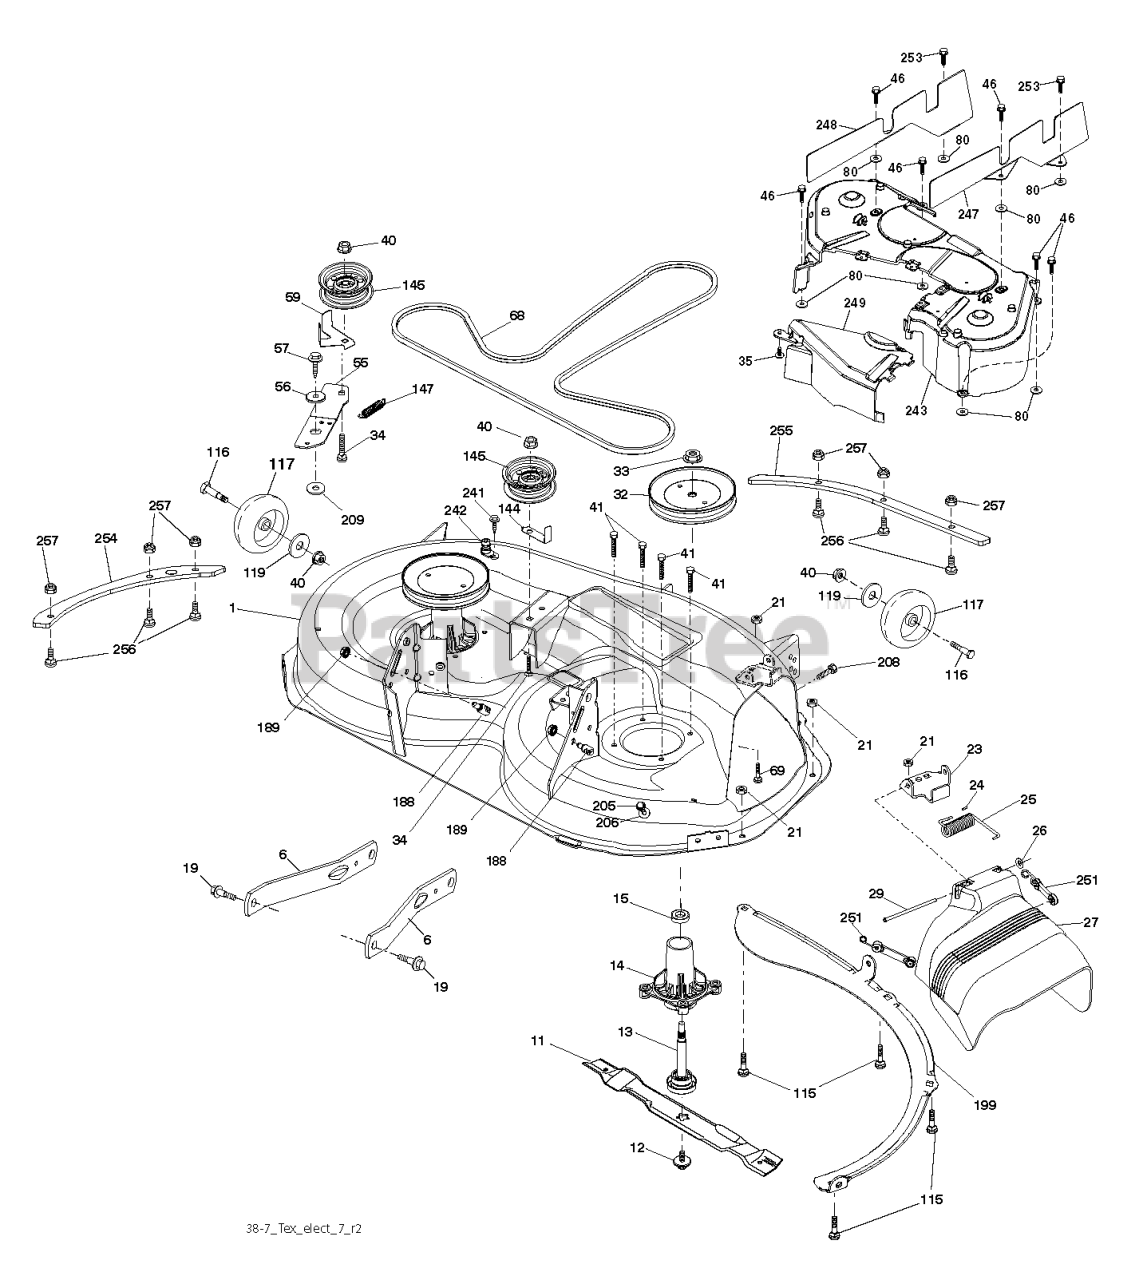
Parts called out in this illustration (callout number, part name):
1	DECK SVC 38" 199770X498
6	ARM.SUSPENSION.MOWER.R
11	BLADE.2 IN 1.38"DECK
12	SCREW.SEMS.7/16-20X1.HEX.HEAD
13	SHAFT ASM.MNDRL.N/GREASEABLE
14	RP.HOUSING.MANDREL.4PT.
15	BEARING.MANDREL.TOP.EXTENDED
19	BOLT.SHOULDER
21	LOCKNUT
23	BRKT.DEFLECTOR.38"2005+
24	CAP-SLEEVE LT
25	SPRING.TORSION.DEFLECT
26	NUT PUSH M
27	SHIELD ASM.DFLCTR MWR.38-7"BLK
29	ROD.HINGE
32	PULLEY MANDREL
33	NUT.FLANGE.LOCK.TOP
34	BOLT.3/8-16X1.50
35	FASTENER.XMAS.TREE
40	NUT LOCK FLG 3/8-16 UNC
41	BOLT.HEX.WASHR.HED.313-18X1.19
46	SCREW.1/4-20X5/8
56	SPACER.RETAINER
57	SCREW 3/8-16X1
59	GUARD, BELT
68	BELT BELT 38' ELEC. DECK
69	BOLT
80	PALNUT 1/4
115	BOLT.CARR.5/16-18X5/8.SHORT
116	BOLT.SHLD."A"2.41."B"1.66
117	WHEEL.GAUGE.RALLY.NARROW
119	WASHER.5/16.FLAT.STE.STD.
144	KEEPER BELT
145	PULLEY.IDLER.48"PRIMARY
147	SPRING.MOWER.DRIVE.ELECTRIC
188	STUD.FASTNER.W/ANTI-ROTATE
189	NUT LOCK HEX FLANGE 5/16-18
199	BAFFLE.VORTEX.FRONT.38"
205	SCREW
208	SCREW 3/8-16X1/2
209	WASHER 12/32X2X10GA
241	SCREW.TT.#10-32X.5.3/8.FLANGE
242	PORT.WASHOUT
243	COVER DECK 38-7
247	GUARD DECK.38IN.RH.ISO X431 BL
248	GUARD.DECK.38IN.LH.X431
249	COVER CABLE CLUTCH
251	ELASTIC STRAP KIT
253	SCREW
254	PLATES.38 DECK RNFRC X431FRONT
255	PLATES.38 DECK RNFRC X431
256	SCREW.BUTTONHEAD.1/4-20X1
257	NUT T
